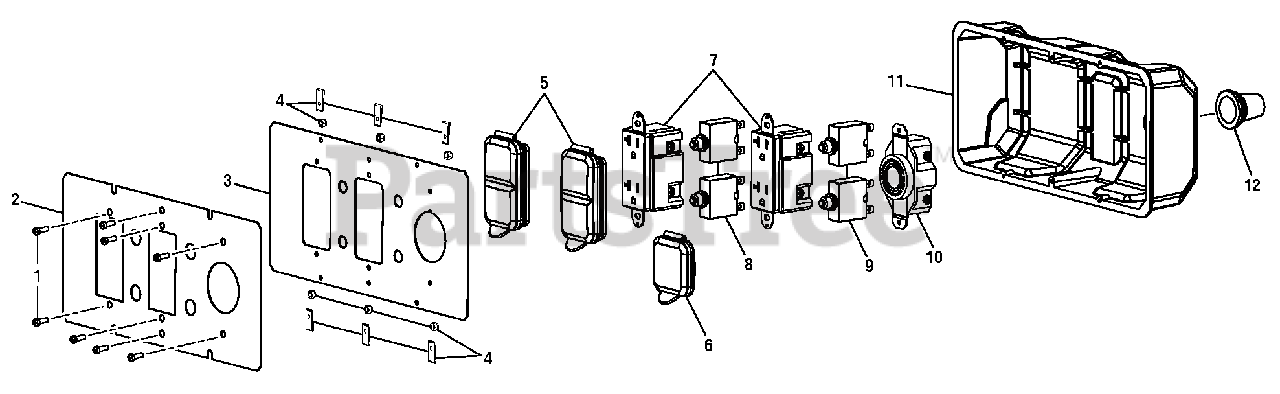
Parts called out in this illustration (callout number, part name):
1	Screw (6-20 x 3/8 in.)
2	Label (Power Outlet)
3	Front Panel
4	U-Clip Nut
5	Outlet Cover (120 Volt)
6	Outlet Cover (240 Volt)
7	Duplex Receptacle (120 Volt)
8	Circuit Breaker, 20 Amp
9	Circuit Breaker, 25 Amp
10	Twist Lock Receptacle (240 Volt)
11	Control Box (Back Panel)
12	Rubber Boot
